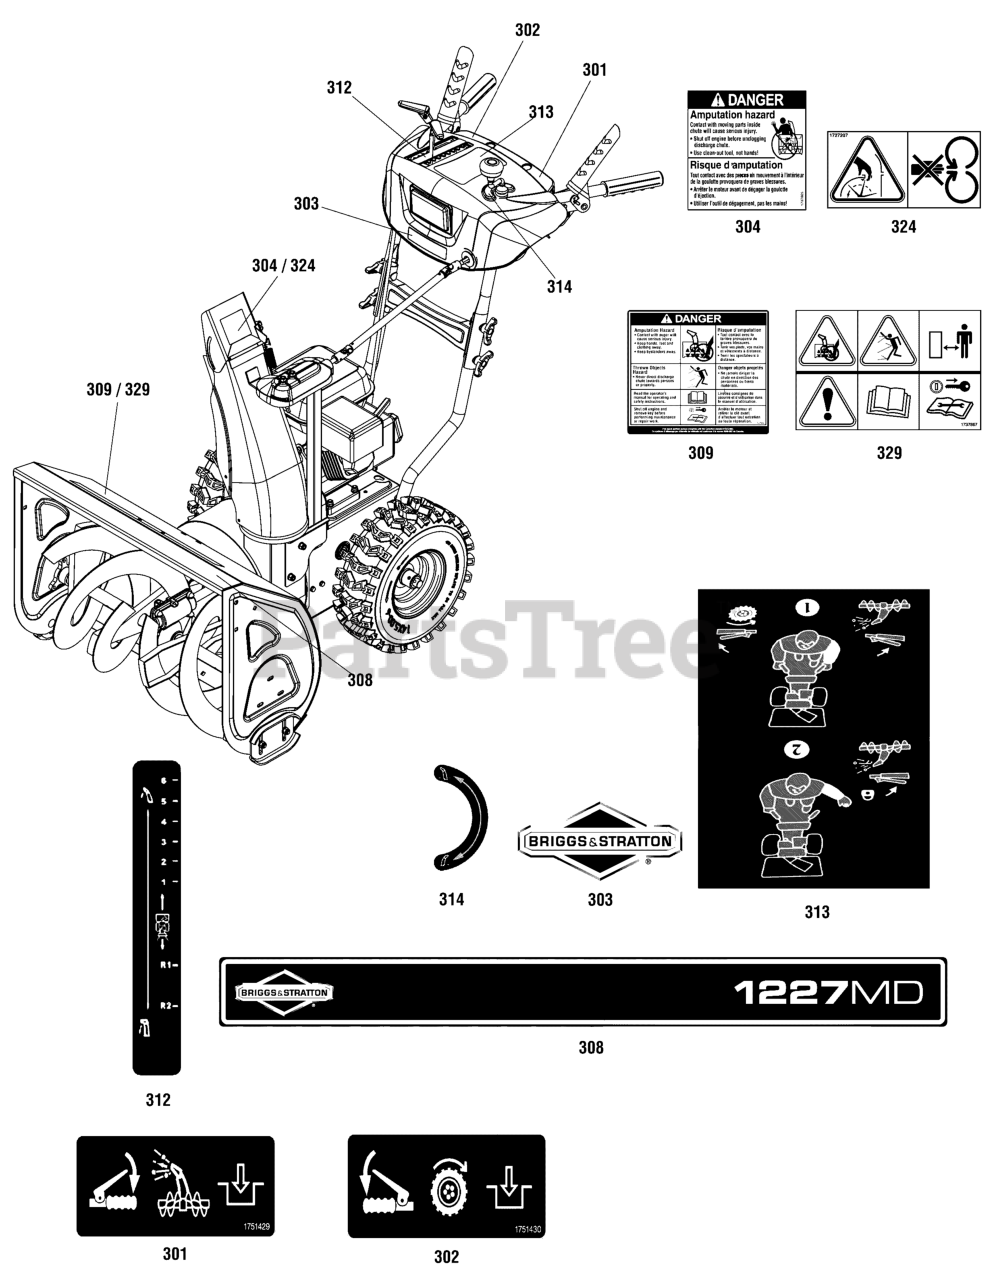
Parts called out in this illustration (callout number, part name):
1	KIT-DECAL, Briggs 1227MD
2	KIT-DECAL, Briggs 1227MD, Export
301	DECAL, Auger Control
302	DECAL, Traction Control
303	*DECAL, Control Panel, Briggs & Stratton
304	DECAL, Danger Chute
309	DECAL, Danger Foot
312	*DECAL, 1-6 Transmission Speed Control
313	*DECAL, Free Hand Operation
314	*DECAL, Chute Rotation
324	DECAL, Chute Warning, Export
329	DECAL, Danger Auger Icons, Export
